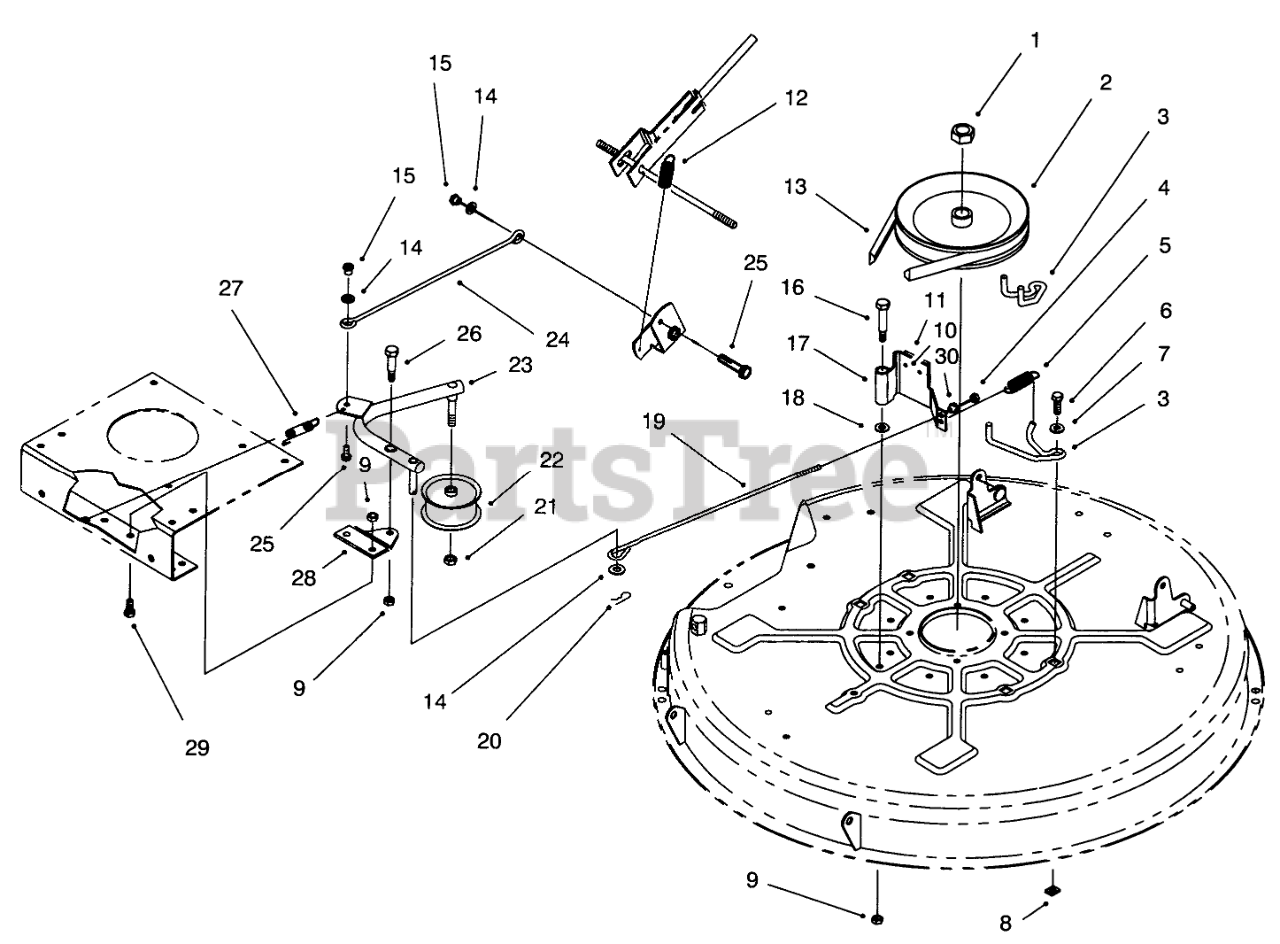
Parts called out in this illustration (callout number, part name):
1	NUT-HEX
2	PULLEY-DECK
3	GUIDE-BELT, DECK
4	NUT-LOCK, NI
5	SPRING-EXTENSION
6	SCREW-HH
7	WASHER-PIVOT
8	NUT-RETAINER
9	NUT-LOCK, NI
10	RIVET-BLIND
11	PAD-BRAKE
12	CABLE SPRING ASM
13	V-BELT
14	WASHER-FLAT
15	POST-MOUNTING, LINKAGE
16	BOLT-SHOULDER
17	Deck Brake Assembly (Incl. Ref. #10 & 11)
18	WASHER-PLAIN
19	ROD-BRAKE, DECK
20	PIN-COTTER
21	NUT-LOCK, NI
22	PULLEY-IDLER
23	Arm-Idler
24	ROD-ENGAGE, DECK
25	SCREW-HHF
26	SCREW-SHOULDER, HH
27	SPRING-RETURN, BRAKE
28	Plate-Idler Mount
29	SCREW-HH
30	BALL-SWIVEL, STOP
